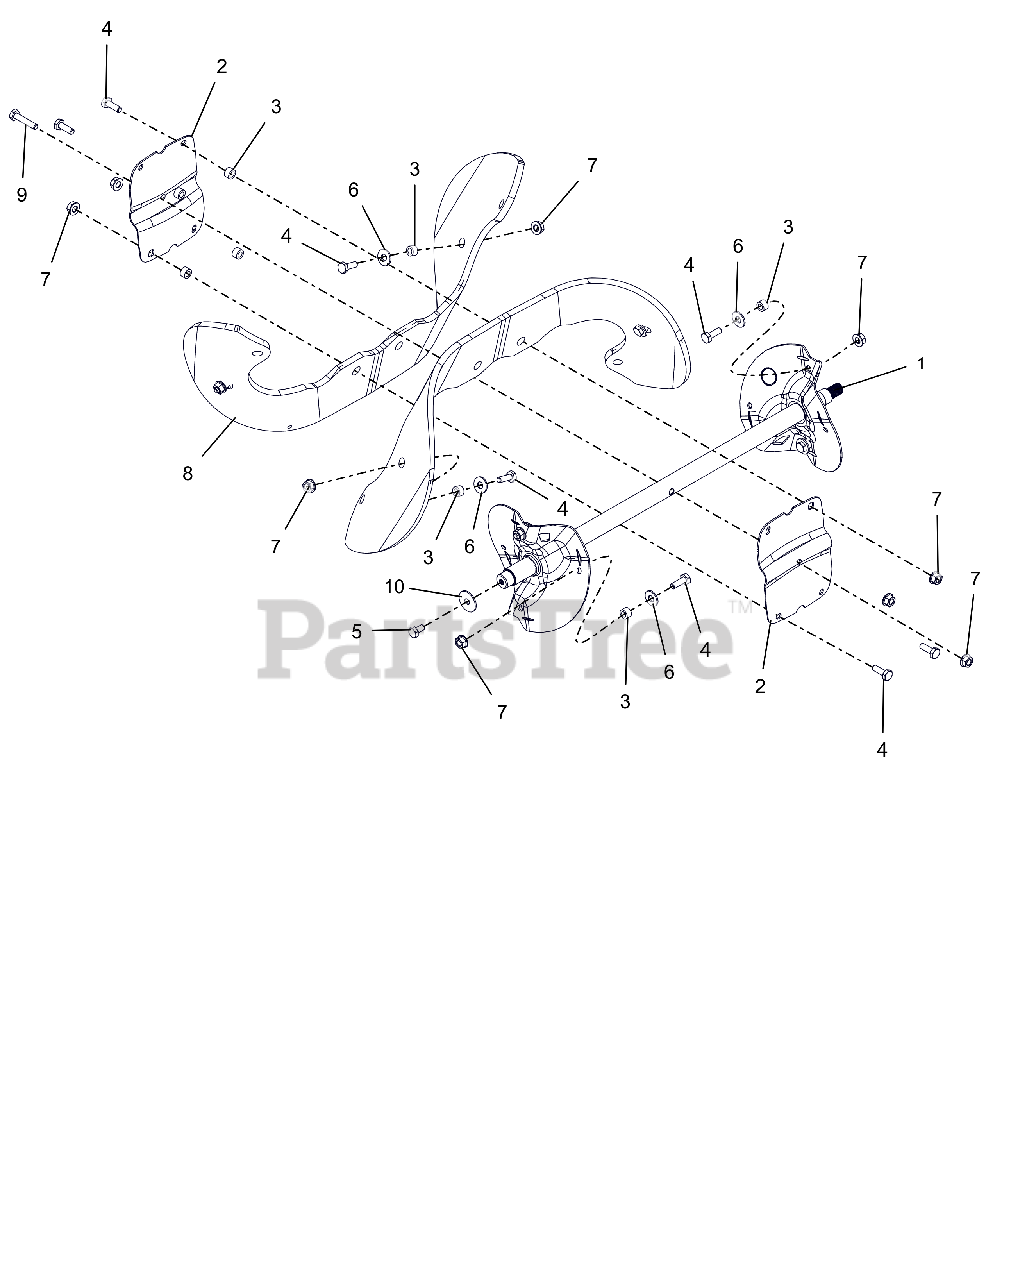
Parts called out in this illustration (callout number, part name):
1	ASSEMBLY, AUGER FRAME
2	PLATE, CENTER AUGER
3	BUSHING, .26 ID X .44 OD X .26
4	@BLT-HEX .25-20X.75 GR5 YWZC
5	@BLT-HEX .25-20X.50 GR5 YWZC
6	@WSHR-FL-STL.312X.734X.065 YWZ
7	@NUT-LK-TOP-FLG .25-20 YWZC
8	KIT, PADDLE REPLACEMENT
9	@BLT-HEX .25-20X1.25 GR5 YWZC
10	WSHR-FL-STL .281X1.000X.063
